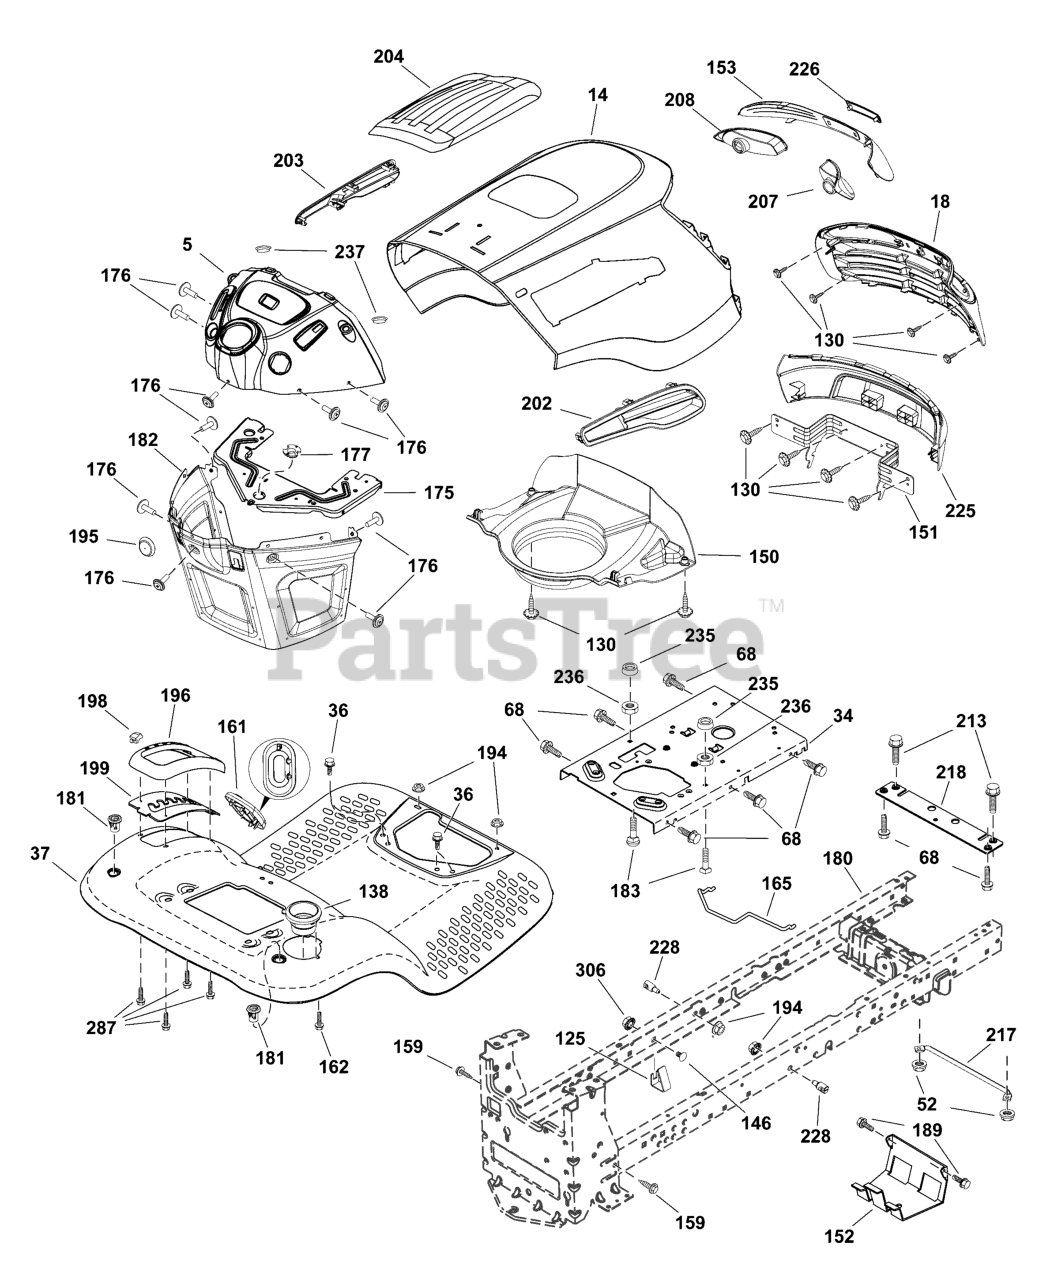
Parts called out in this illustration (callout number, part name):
34	Plate Engine Welded Chassis
36	Screw 5/16-18 X 3/4 Smgml Tap/R
52	Nut, Hex, Crownlock 5/16-18
68	SCREW, 5/16-18 X 1/2, Thread Roll
125	Clip Fuel Line
130	Screw #10 x 0.750 BOS Thread
138	CUPHOLDER
150	DUCT, Air
151	Bracket Pivot Lasr/Elte/Husqlt
152	Shield Browning/Debris
153	LENS, Bar Pred
159	Screw 3/8-16 x .75 Smgml Tap/R.Z
161	Window Fuel
162	Screw Hex Wsh Hi-Lo 1/4 X 1/2 Unc
165	Support Tank Rear
175	CROSSMEMBER
176	Screw #10-24X5/8 Rnd Qudrx Gim
177	Bushing Steering Yt/Gt
180	Chass Wldmt Tl 12 Ga/2Pc
181	Bushing Mnt Fend Crgo Blk Tex
182	Hex Capscrew, 5/16"-18 x 6-1/2" lg.
183	Bolt Full Thd 5/16-18 x 1-1/4
189	Screw 5/16-18 X 3/4 Smgml Tap/Bl
194	Nut, Lock Hex Flange 5/16-18 Unc
195	PLUG, Lower Dash Hole
196	Console Asm. Deck Lift
198	Indicator Deck Lift
199	Plate Deck Lift
202	VENT, RH Side Hood
203	VENT, LH Side Hood
204	VENT, Top
207	Insert Lens Reflective RH
208	Insert Lens Reflective LH
213	CAPSCREW, 5/16-18 X 3/4 GR. 5 ZD
217	Rod Pivot Hood
218	X-Piece Hood Stop Non/Stealth
225	BUMPER, Snapper
226	PLATE, Snapper Logo
228	Stud Fastner W/'D'anti-Rotatio
235	Spacer Fender
236	Nut Center Lock 5/16-18 Unc
237	Plug Mount Cargo
287	Screw Hex Washead 1/4-20 X 3/8
306	NUT, 3/8-16, Lock
